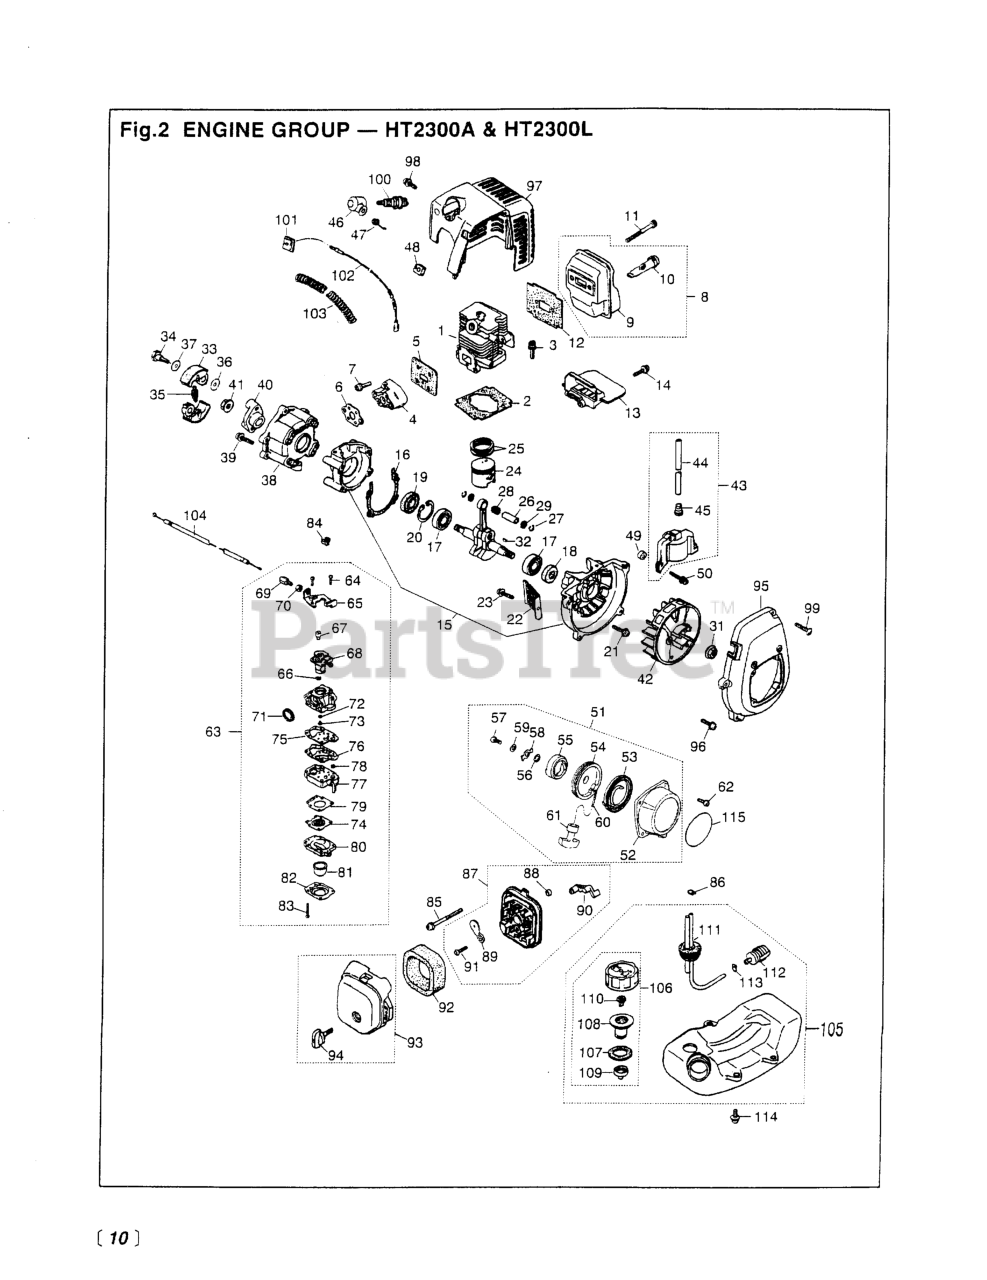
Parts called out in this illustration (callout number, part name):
1	CYLINDER
3	BOLT, M5 X 22
7	SCREW, M5X20 (RPLS.1400-75510)
8	MUFFLER ASSEMBLY
10	ARRESTER (RPLS 5850-15140)
11	BOLT, M5 x 50
12	GASKET, MUFFLER
14	SCREW, M4 X 16
15	CRANKCASE COMP.
17	BEARING
18	SEAL, OIL (RPLS 1100-21210)
19	SEAL, OIL (RPLS 1140-21220)
20	RING, SNAP, M28 x 1.2
21	BOLT, M5 X 30
23	SCREW,M5 X 14 (RPLS 1400-15510
24	PISTON (REPLACES 1140-41110)
25	RING, PISTON (RPLS 1850-41210)
26	PIN, PISTON 5x8x26
27	RING, SNAP (RPLS 1101-41320)
29	WASHER
30	CRANKSHAFT (RPLS -42000)
32	KEY
33	SHOE (RPLS 1100-51114)
34	BOLT
35	SPRING, CLUTCH (RPLS-51220)
36	WASHER, FLAT (USE 182303)
38	CASE, CLUTCH
39	SCREW
40	PLATE, CLUTCH
42	ROTOR (RPLS 5601-71110)
44	CORD
45	CAP
47	SPRING
48	GROMMET
49	SPACER (RPLS -71260)
50	BOLT
52	CASE, RECOIL
53	SPRING, SPIRAL
56	WASHER
57	SCREW
58	RETAINER (RPLS 1861-75161)
59	WASHER
60	ROPE
62	SCREW, M4 x 12
63	CARBURETOR (WYJ-114-1)
64	SCREW
65	BRACKET
66	RING
67	SWIVEL
68	VALVE ASSY
69	SCREW, CABLE ADJUSTER
70	NUT, CABLE ADJUSTER
71	RING, PACKING
72	RING, O
74	DIAPHRAGM (USE 4810-81260)
75	GASKET, PUMP
76	DIAPHRAGM
77	BODY, PUMP
79	GASKET, DIAPHRAGM
80	BODY, PURGE
81	PUMP, PRIMING
82	COVER, PUMP
83	SCREW
84	CAP, CABLE END
85	SCREW, M5 x 60
86	CLIP
88	SLEEVE
89	PLATE, CHOKE (RPLS-82130)
90	LEVER, CHOKE
91	SCREW (REPLACES 50030272)
92	ELEMENT
95	COVER, FAN
96	SCREW, M5X20 (RPLS.1400-75510)
97	COVER, ENGINE(USE-32101)
98	SCREW, M5 x 12
99	SCREW, HOUSING
102	CORD COMP.
104	CABLE COMPL (RPLS-82100)
107	PACKING
109	HOLDER, CAP
110	VALVE (NLA WHEN OUT)
111	PIPE COMPLETE
112	FILTER ASSY
113	CLIP (REPLACES 2841-31280)
114	SCREW
115	LABEL, RECOIL
